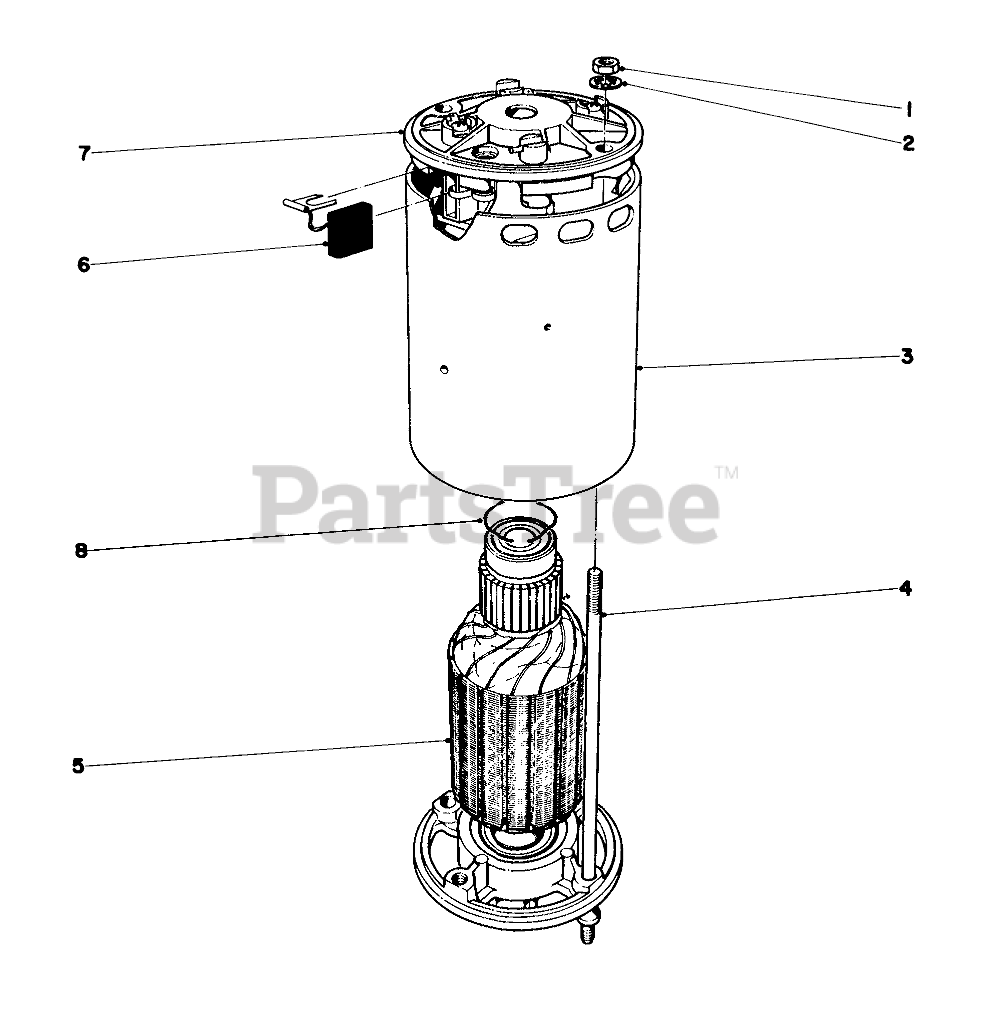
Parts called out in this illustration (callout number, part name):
1	NUT-HEX
2	WASHER-LOCK, INTERNAL
3	Motor Shell
4	Tie Bolt
5	Armature Assy. w/Bearings
6	Brush-Motor
7	Upper End Plate Assembly of Brushes
8	Thrust Spring
